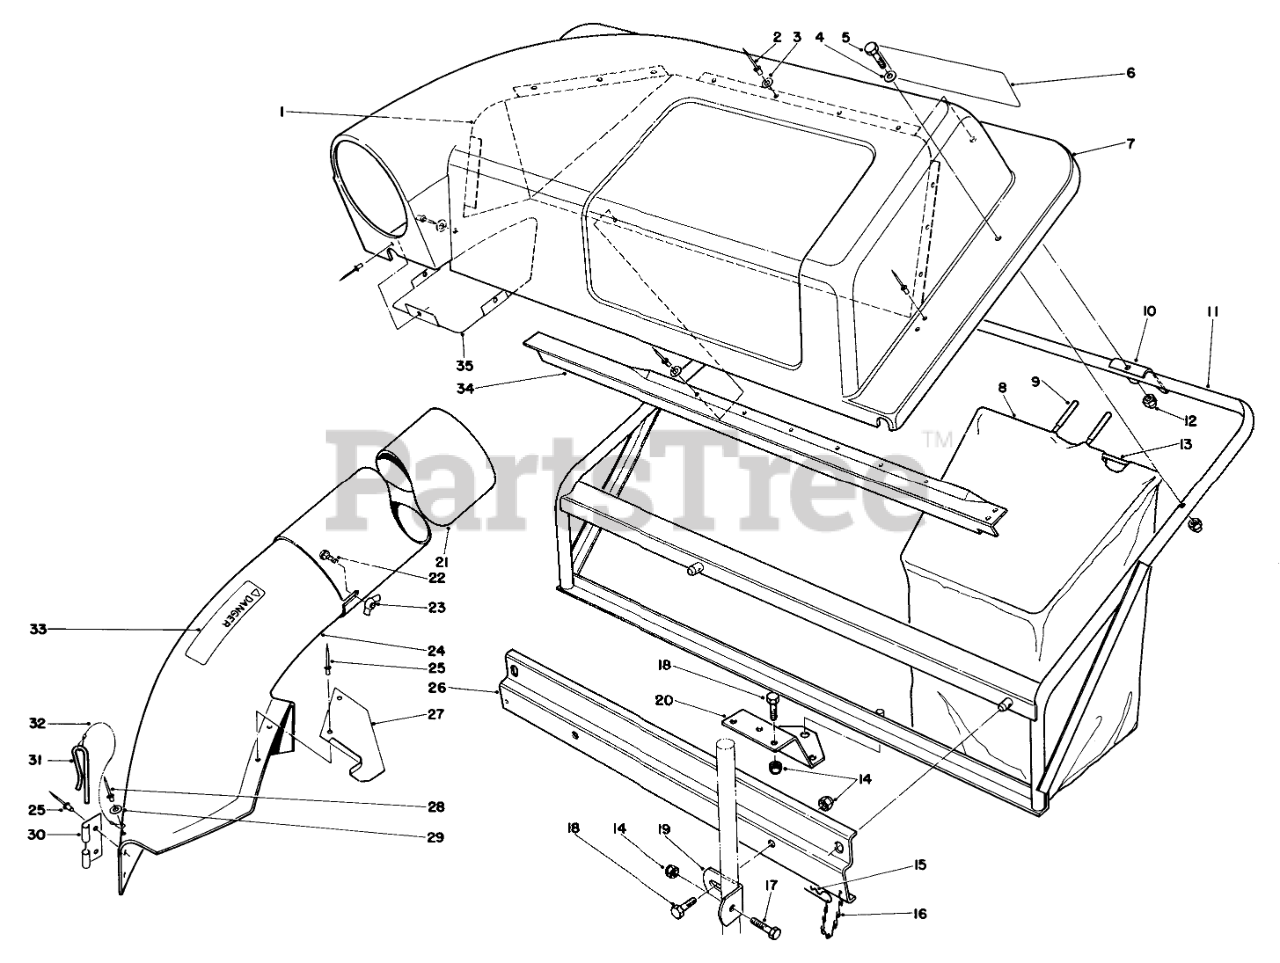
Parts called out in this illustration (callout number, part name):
1	Screen Cover
3	WASHER-FLAT
4	WASHER-PLAIN
5	SCREW-HH
6	TWIN BAGGER DECAL
7	Cover
9	GRIP-HANDLE, BAG
10	BAG FRAME BRKT
11	NUT-LOCK, CAP
12	Frame
13	Frame-Bag
14	NUT-LOCK, CONE
15	PIN-HAIR
16	6-LINK CHAIN W/HOOK
17	SCREW-HH
18	SCREW-HH
19	Bracket Mtg. Grass Catcher
20	Plate-Mtg. Grass Catcher
21	TUBE(ROUND&LONG)
22	BOLT-CARR
23	NUT-WING SPECL
24	Chute Assembly (Incl. Ref. #25, 27-33)
25	RIVET-BLIND
26	Bracket Frame Support
27	CHUTE SUPT BRKT
28	RIVET-BLIND
29	WASHER-PLAIN
30	BRACKET-MOUNTING, CHUTE
31	PIN-LOCKING, CHUTE
32	LANYARD
33	Decal-Chute
34	SCREEN SUPT BRKT B
35	Shield Cover
